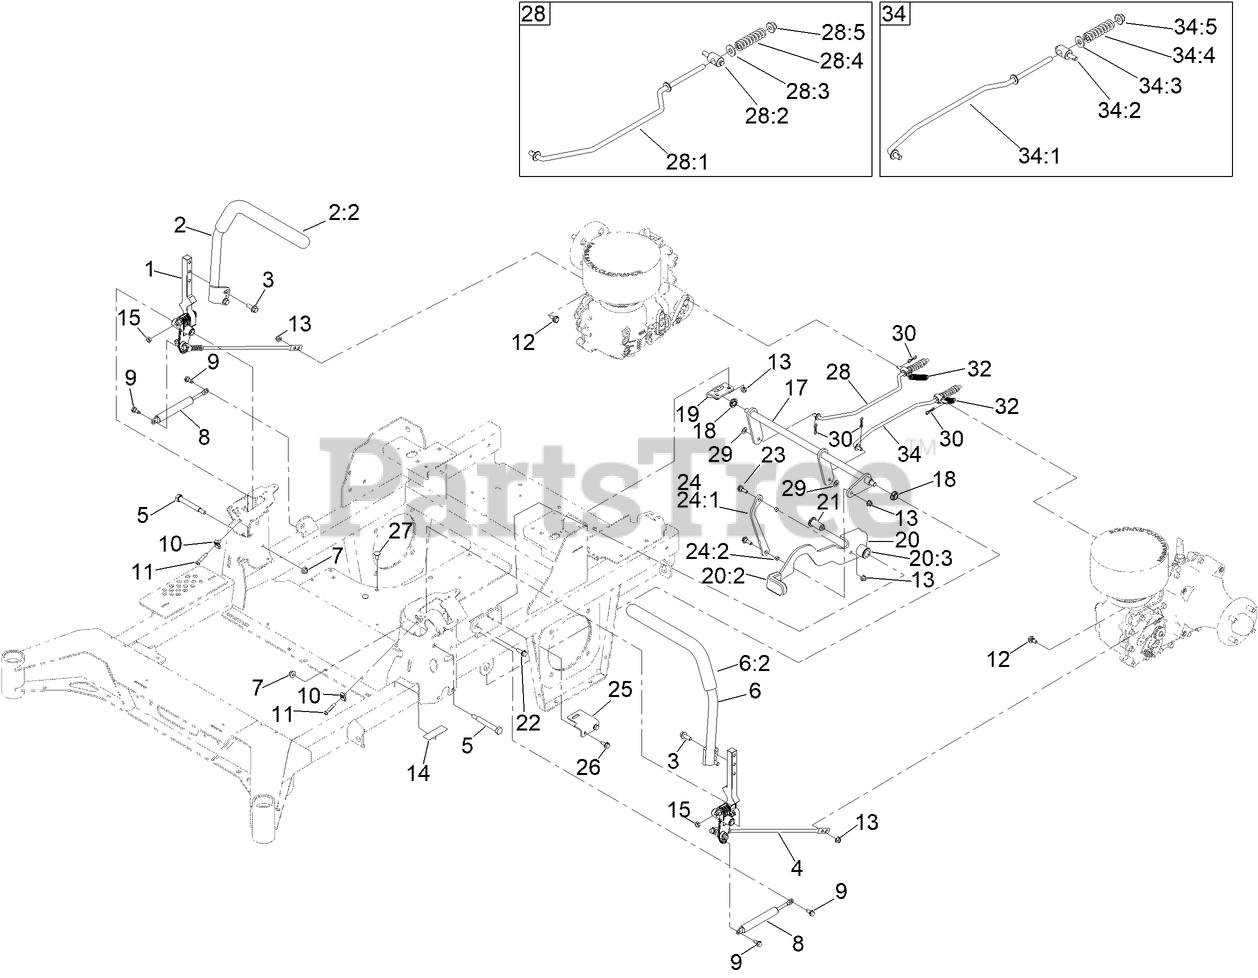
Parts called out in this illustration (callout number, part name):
1	MOTION CONTROL ASM-RH
2	HANDLE ASM - RH
2:2	GRIP-CONTROL, LEVER
3	SCREW-HHF
4	MOTION CONTROL ASM-LH
5	BOLT-PIVOT
6	HANDLE ASM - LH
6:2	GRIP-CONTROL, LEVER
7	NUT-HF, NI
8	DAMPER
9	SCREW-SHOULDER
11	SCREW-HSBH
12	BOLT-SHOULDER,HFH
13	NUT-HF, NI
14	DECAL-BRAKE, PARKING
15	NUT-JAM
17	BRAKE ASM
18	BEARING-SPHERICAL
19	BRACKET-BRAKE
20	BRAKE LEVER ASM W/GRIP
20:2	BUSHING-FLANGE
20:3	GRIP-LEVER
21	PIVOT-HANDLE
22	SCREW-HHF
23	SCREW-SHOULDER
24	BRAKE LINK ASM
24:1	PLATE-LINK, HANDLE
24:2	BUSHING-SLEEVE
25	PLATE-SWITCH
26	SCREW-HWHTF
27	SCREW-CARR
28	RH BRAKE ROD ASM
28:1	ROD-BRAKE, RH
28:2	FITTING-ROD
28:3	WASHER-FLAT
28:4	SPRING-COMPRESSION
28:5	NUT-HF, NI
29	WASHER-FLAT
30	PIN-COTTER, LOCKING
32	SPRING-EXTENSION
34	LH BRAKE ROD ASM
34:1	ROD-BRAKE, LH
34:2	FITTING-ROD
34:3	WASHER-FLAT
34:4	SPRING-COMPRESSION
34:5	NUT-HF, NI
